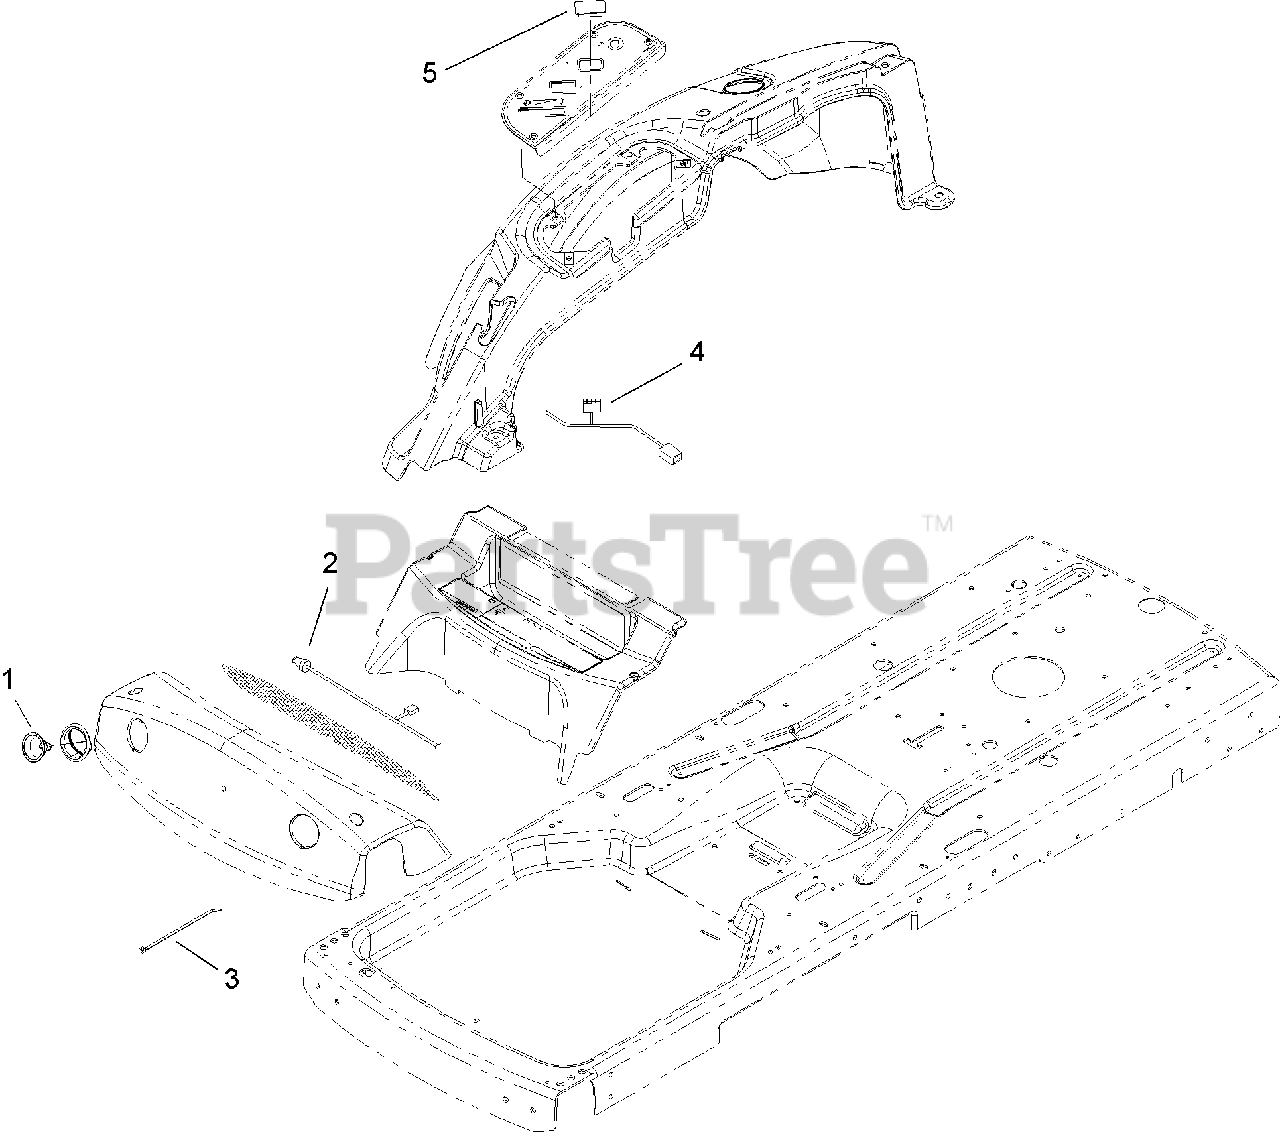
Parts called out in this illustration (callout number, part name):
1	LIGHT-HALOGEN
2	HARNESS-HEADLIGHTS, FOOTREST
3	TIE-CABLE
4	HARNESS-HEADLIGHTS, CHASSIS
